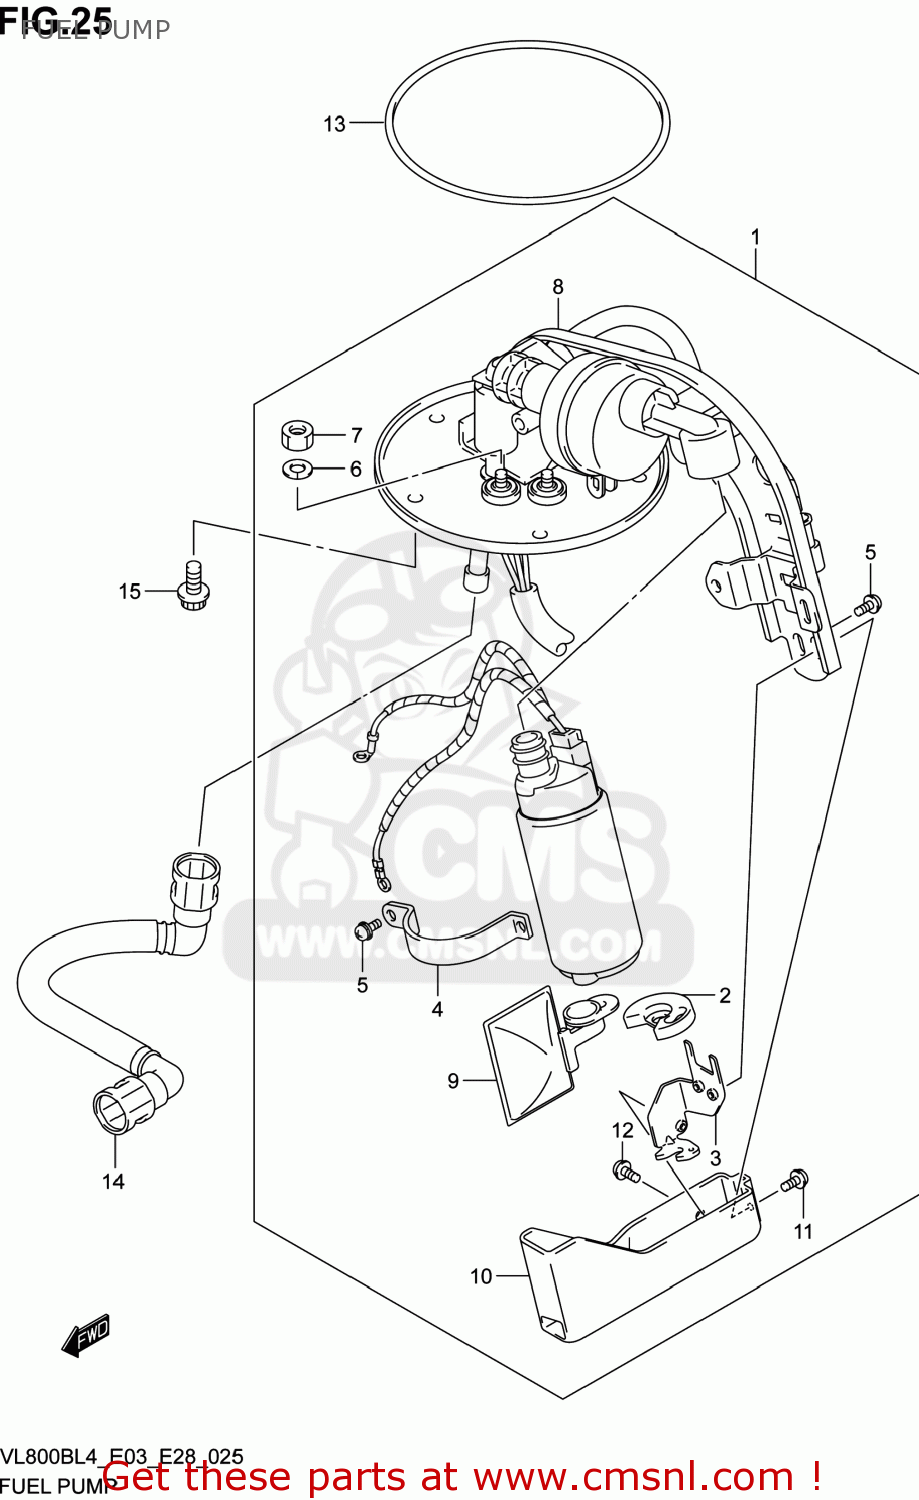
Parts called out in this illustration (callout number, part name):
1	PUMP ASSY,FUEL
2	CUSHION
3	HOLDER
4	BAND,FUEL PUMP
5	SCREW
6	WASHER,SPRING
7	NUT
8	PLATE ASSY
9	STRAINER
10	VESSEL
11	SCREW
12	SCREW
13	O RING,FUEL PUMP
14	HOSE,FUEL
15	BOLT
